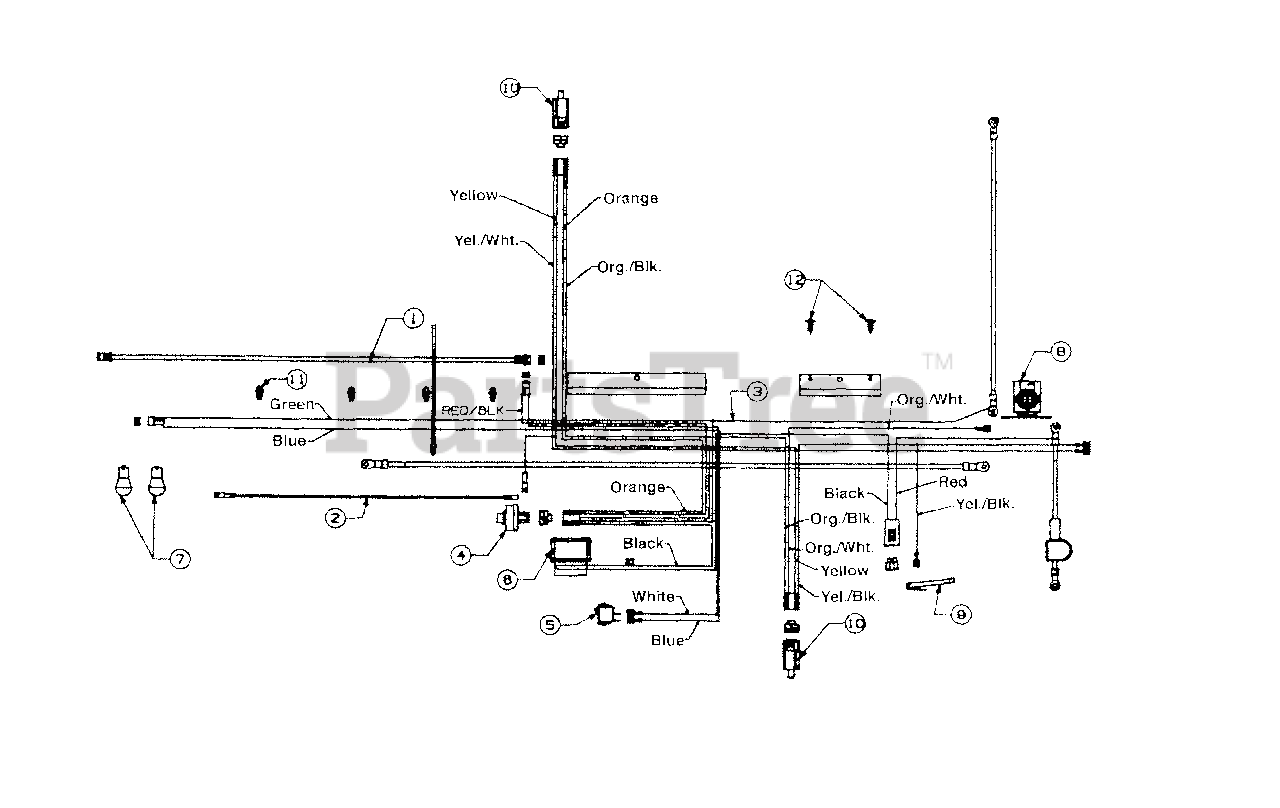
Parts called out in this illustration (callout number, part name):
1	Harness Adapter (Alt.)
2	Harness Adapter
3	Wire Harness w/Light Switch & Amp
4	Ignition Switch
5	Light Switch
6	Ammeter
7	Bulb
8	Solenoid
9	Safety Switch (Reverse)
10	Safety Switch
11	Wire Retainer Clip
12	Ratchet
